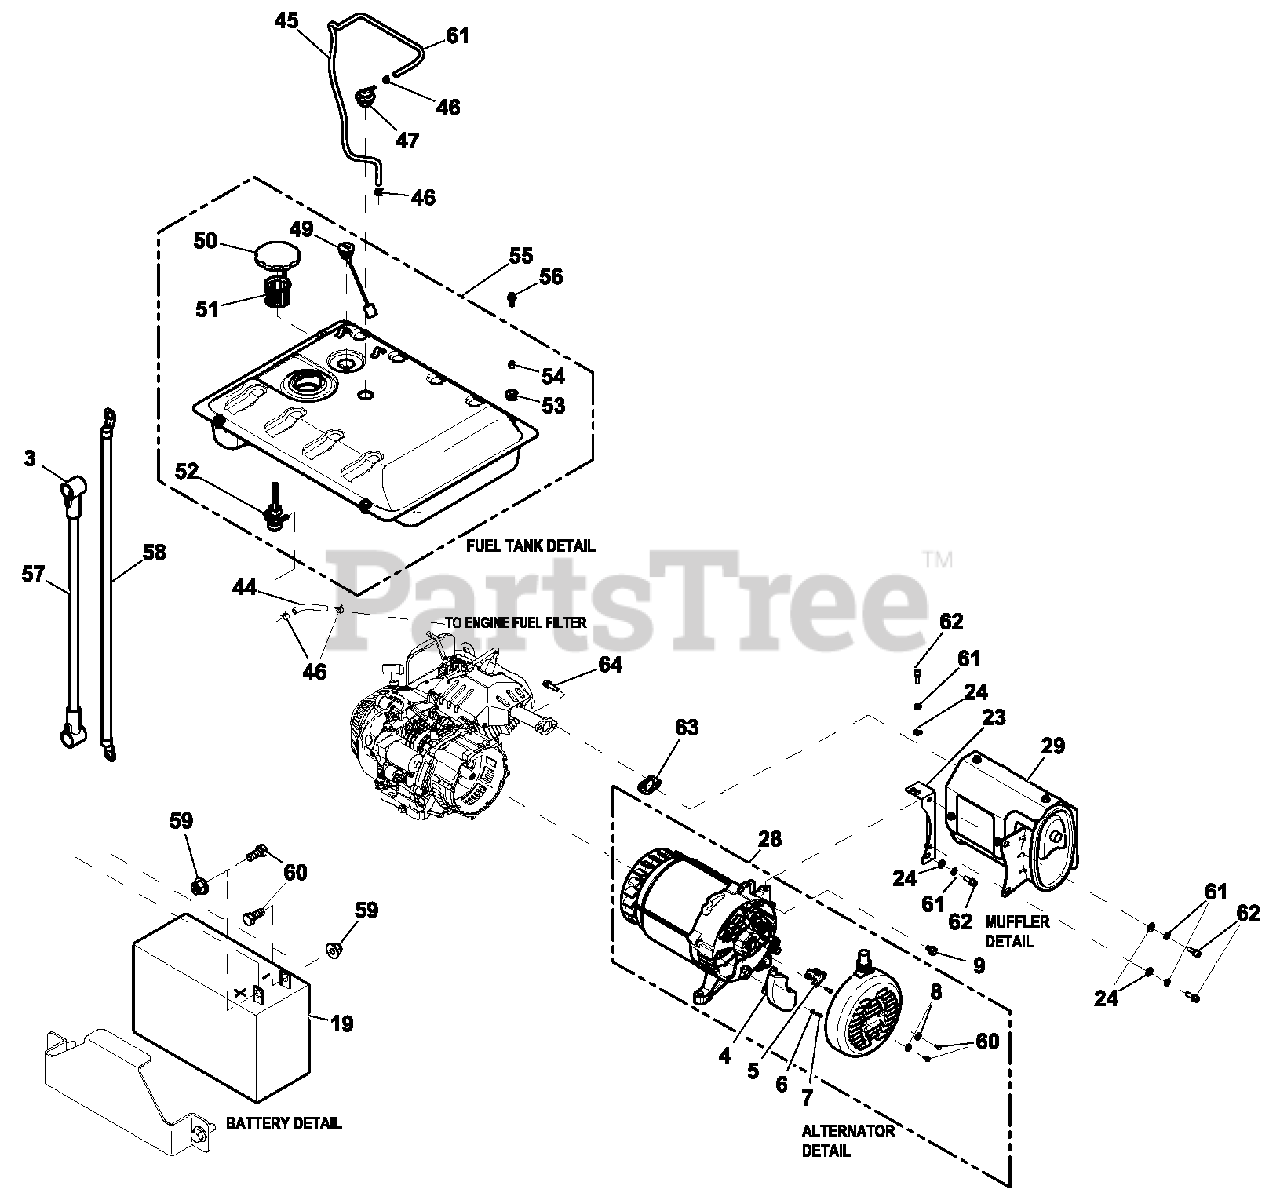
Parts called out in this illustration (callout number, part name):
3	BOOT, VINYL STARTER-SOLENOID
4	AVR 5.5-7.5KW ALT
5	ASSEMBLY,BRUSH
6	WASHER FLAT M5
7	SCREW HHC M5-0.8 X 16 G8.8
8	WASHER LOCK M5
9	SCREW HHFCS M6-1 X 12 G8.8
19	BATTERY 12V10AH SEALED
23	BRACKET, MUFFLER 389CC
24	WASHER FLAT 5/16-M8 ZINC
28	ALT 6500W CU-AL BRUSH TYPE
29	ASSY MUFFLR GP5.5-6.5KW
44	FUEL HOSE 4 ID X 8.5OD X 55MM
45	HOSE FORMED ROV-AIRBOX 420CC
46	CLAMP HOSE BAND .41
47	ASSEMBLY ROV
50	ASSY GAS CAP SEALED - BLACK
51	STRAINER, FUEL CAP
52	VALVE, FUEL SHUT OFF
53	RUBBER MOUNT,10.3 ID X 11 HGT
54	ANTI-CRUSH 10.8OD 9ID 10LG
55	FUEL TANK ASSY 8 GAL
56	SCREW HHFC M8-1.25 X 20 W/M10
57	WIRE ASSY 8GA 11" RED
58	WIRE ASSY 8GA 17" BLACK
59	NUT FLANGE M5-0.8 NYLOCK
60	SCREW HHC M5-0.8 X 12 C8.8
61	WASHER LOCK M8-5/16
62	SCREW HHC M8-1.25 X 30 C8.8
63	GASKET, EXHAUST, 389CC
64	SCREW HHC M8-1.25 X 20 C8.8
